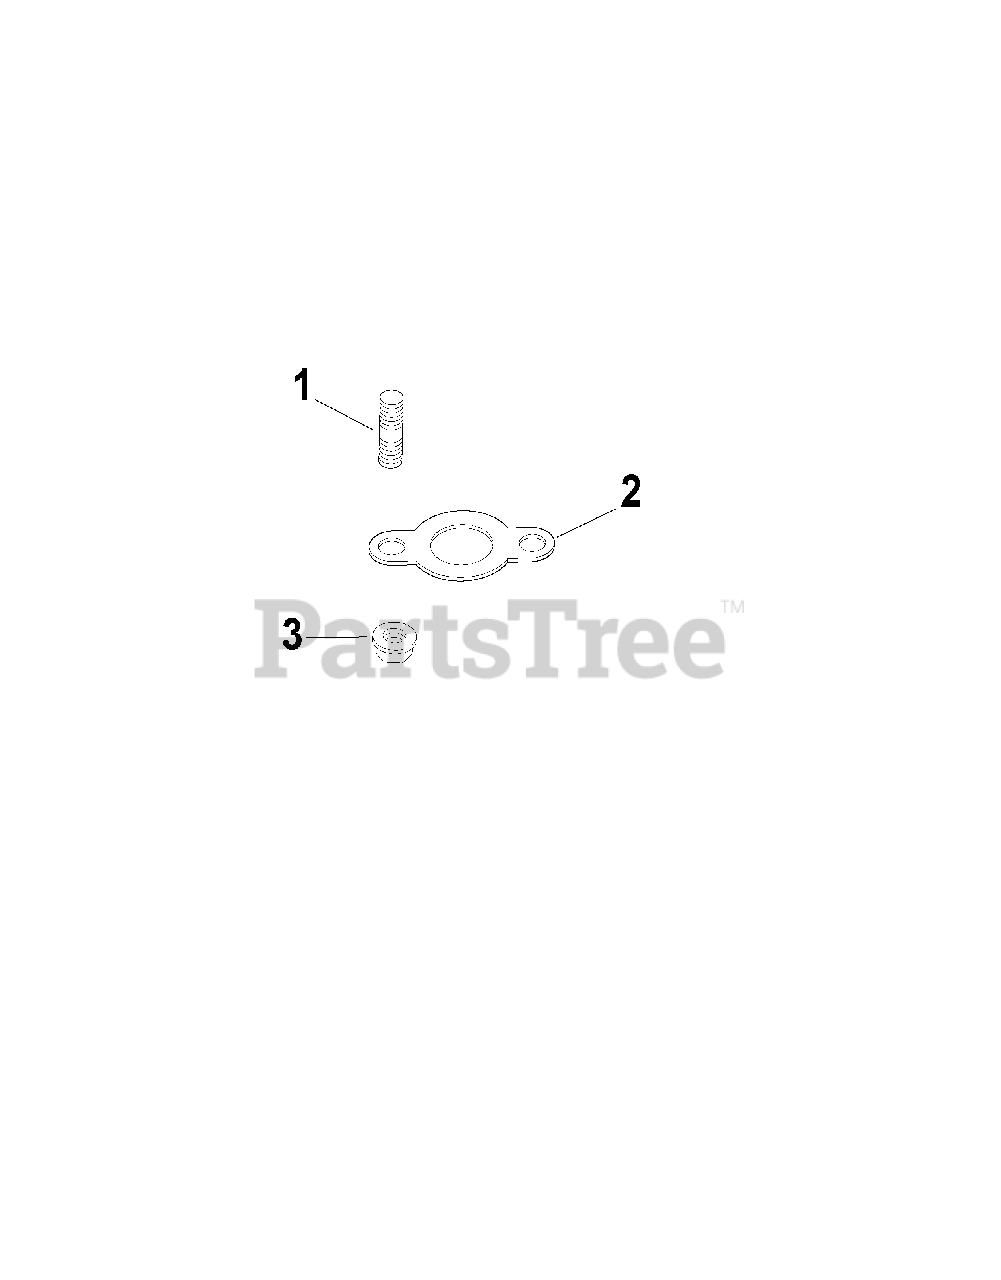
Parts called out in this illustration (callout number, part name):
1	Stud M8x1.25x33 (4)
2	Gasket, exhaust manifold (2)
3	Nut, hex. flange M8x1.25 (5)
